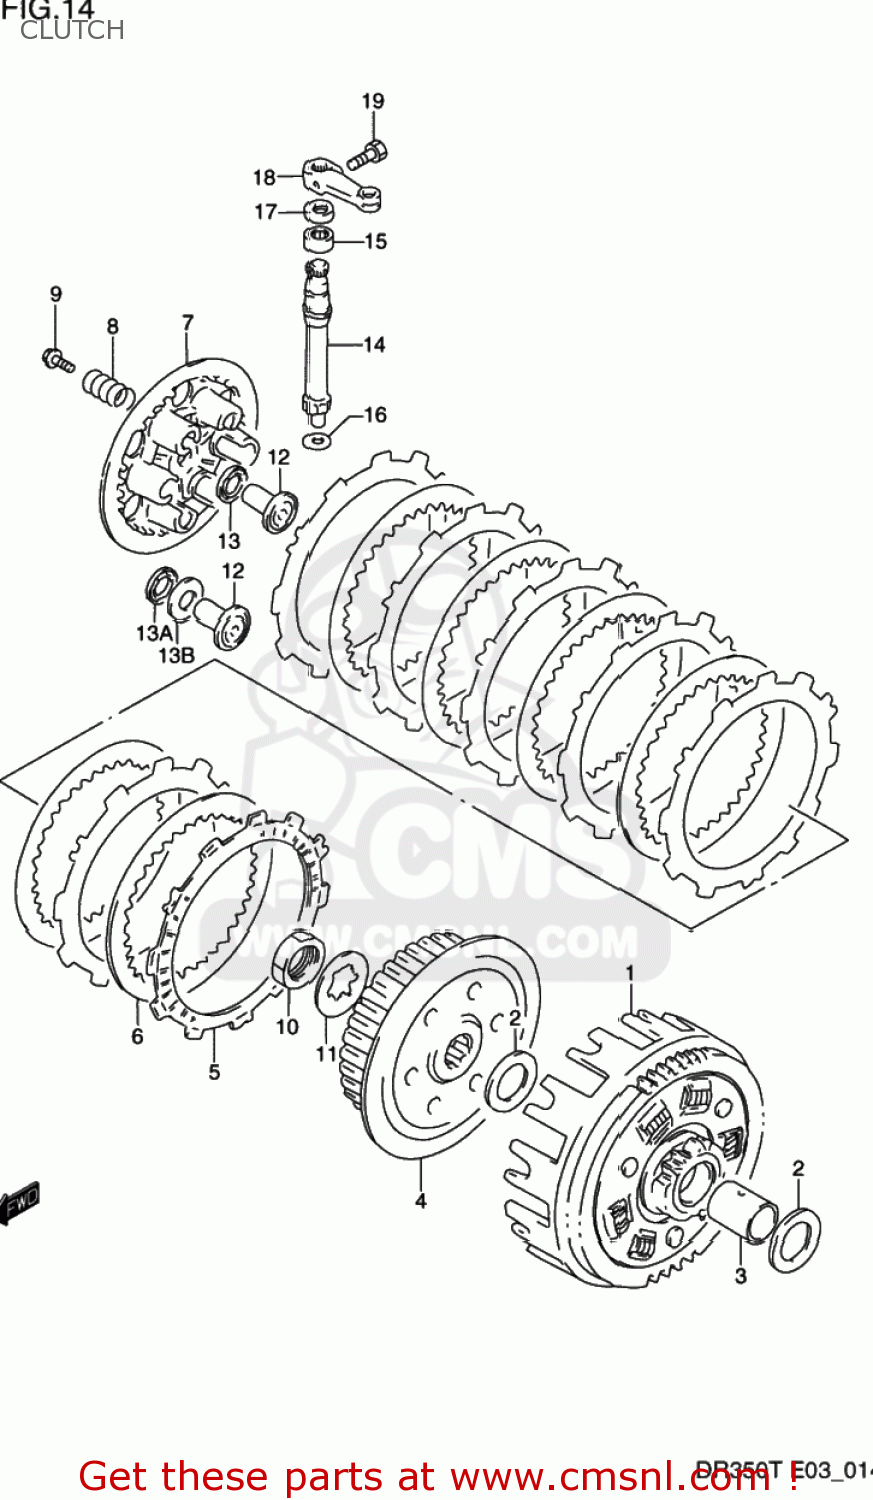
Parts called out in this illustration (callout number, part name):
1	GEAR ASSY,PRI DRIVEN(62/15
2	WASHER
3	SPACER(20X25X29)
4	HUB,CLUTCH SLEEVE
5	PLATE,CLUTCH DRIVE (NAS)
6	PLATE,CLUTCH DRIVEN (NAS)
7	DISC,CLUTCH PRESSURE
8	SPRING
9	BOLT 5X16
10	NUT (20MM)
11	WASHER,LOCK
12	RACK,CLUTCH RELEASE
13	BEARING(10X22X2.8)
13A	BEARING(10X24X2)
13B	WASHER
14	PINION,CLUTCH RELEASE
15	BEARING(12X16X10)
16	WASHER
17	SEAL,OIL(10X17X5)
18	ARM,CLUTCH RELEASE
19	BOLT
